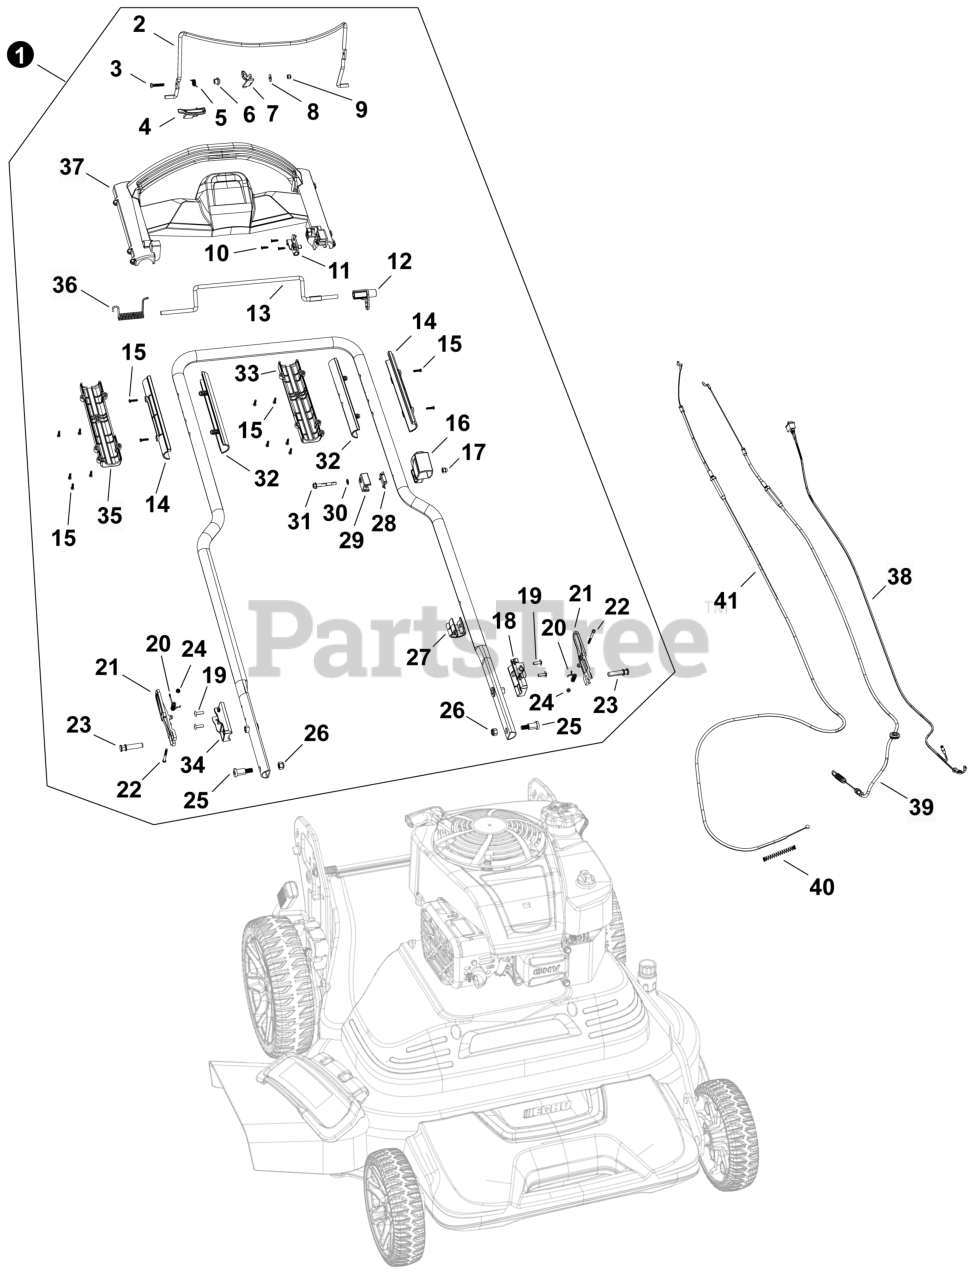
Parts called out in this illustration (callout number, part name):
1	HANDLEBAR ASSY.
2	BAIL, BLADE BRAKE
3	SCREW
4	HANDLE, BAIL INTERLOCK
5	BUSHING, INTERLOCK
6	SPRING, INTERLOCK
7	LEVER, INTERLOCK
8	WASHER
9	NUT
10	SCREW
11	COVER, CABLE
12	BLOCK, ROTATION
13	BAIL, DRIVE
14	SLEEVE, LEFT HANDLEBAR
15	SCREW
16	HOUSING, SWITCH
17	NUT
18	PLATE, LOWER LEFT HANDLEBAR
19	RIVET
20	SPRING
21	PLATE, HANDLEBAR ADJ.
22	SCREW
23	PIN
24	NUT
25	BOLT
26	NUT, M8
27	CLAMP, WIRE
28	SPACER
29	BLOCK, CABLE
30	WASHER
31	BOLT
32	SLEEVE, RIGHT HANDLEBAR
33	COVER, LEFT LOWER HANDLE
34	PLATE, LOWER RIGHT HANDLEBAR
35	COVER, RIGHT LOWER HANDLE
36	SPRING, DRIVE BAIL
37	HANDLE, OPERATOR
38	WIRE ASSY., ON/OFF SWITCH
39	CABLE ASSY., DRIVE
40	SPRING, CABLE RETURN
41	CABLE ASSY., BLADE DRIVE
